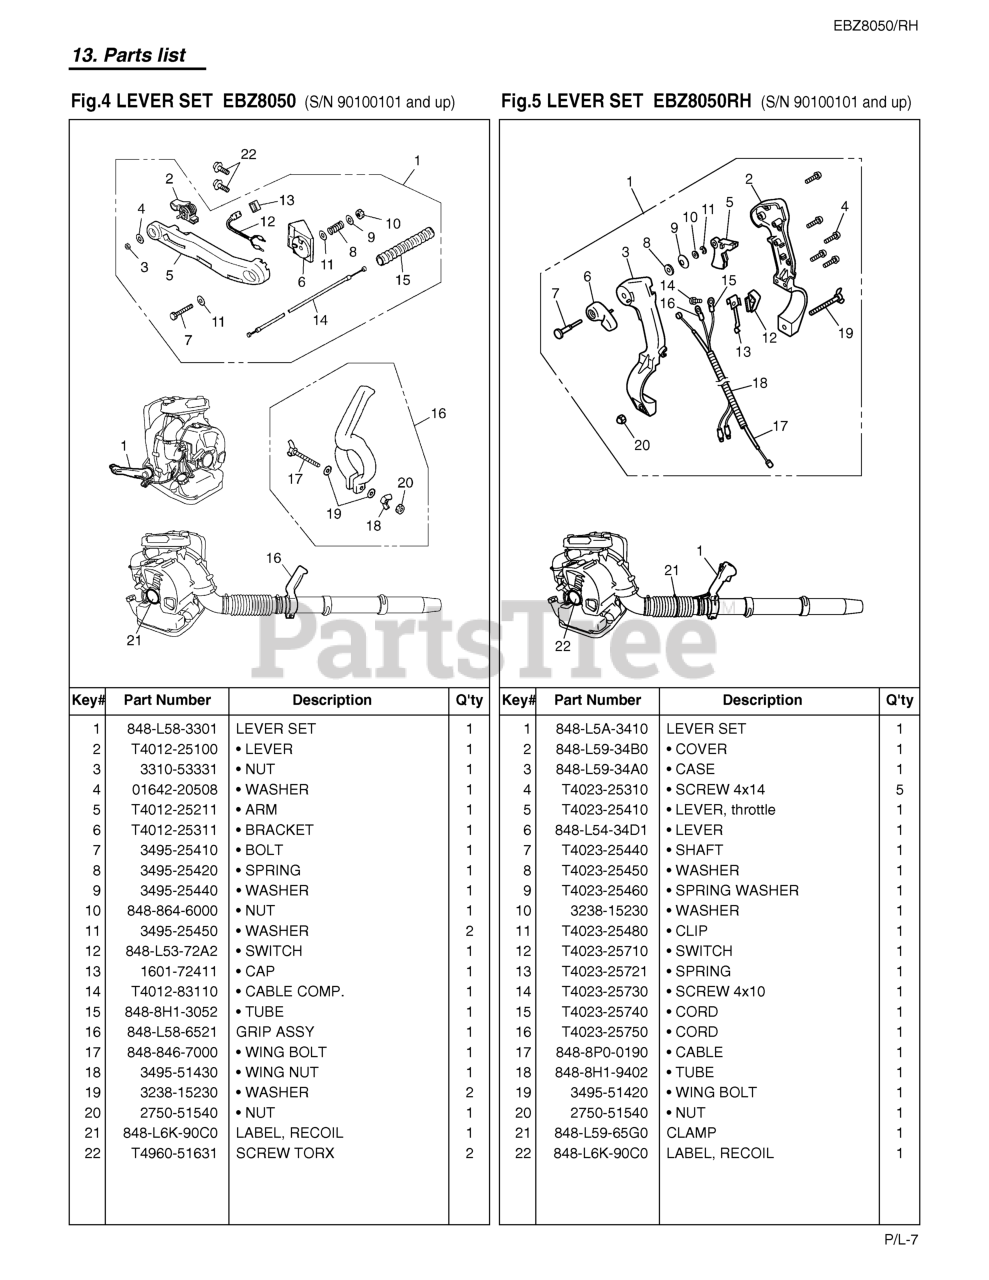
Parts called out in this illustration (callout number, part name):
1	LEVER SET
2	LEVER
3	NUT
4	WASHER
5	ARM
6	BRACKET
7	BOLT
8	SPRING
9	WASHER
10	NUT
11	WASHER
12	SWITCH
13	CAP SWITCH
14	CABLE COMP
15	TUBE (REPLACES T4012-25610)
16	GRIP ASSY
17	WING BOLT
18	NUT, WING
19	WASHER
20	NUT
21	LABEL, RECOIL
22	SCREW
